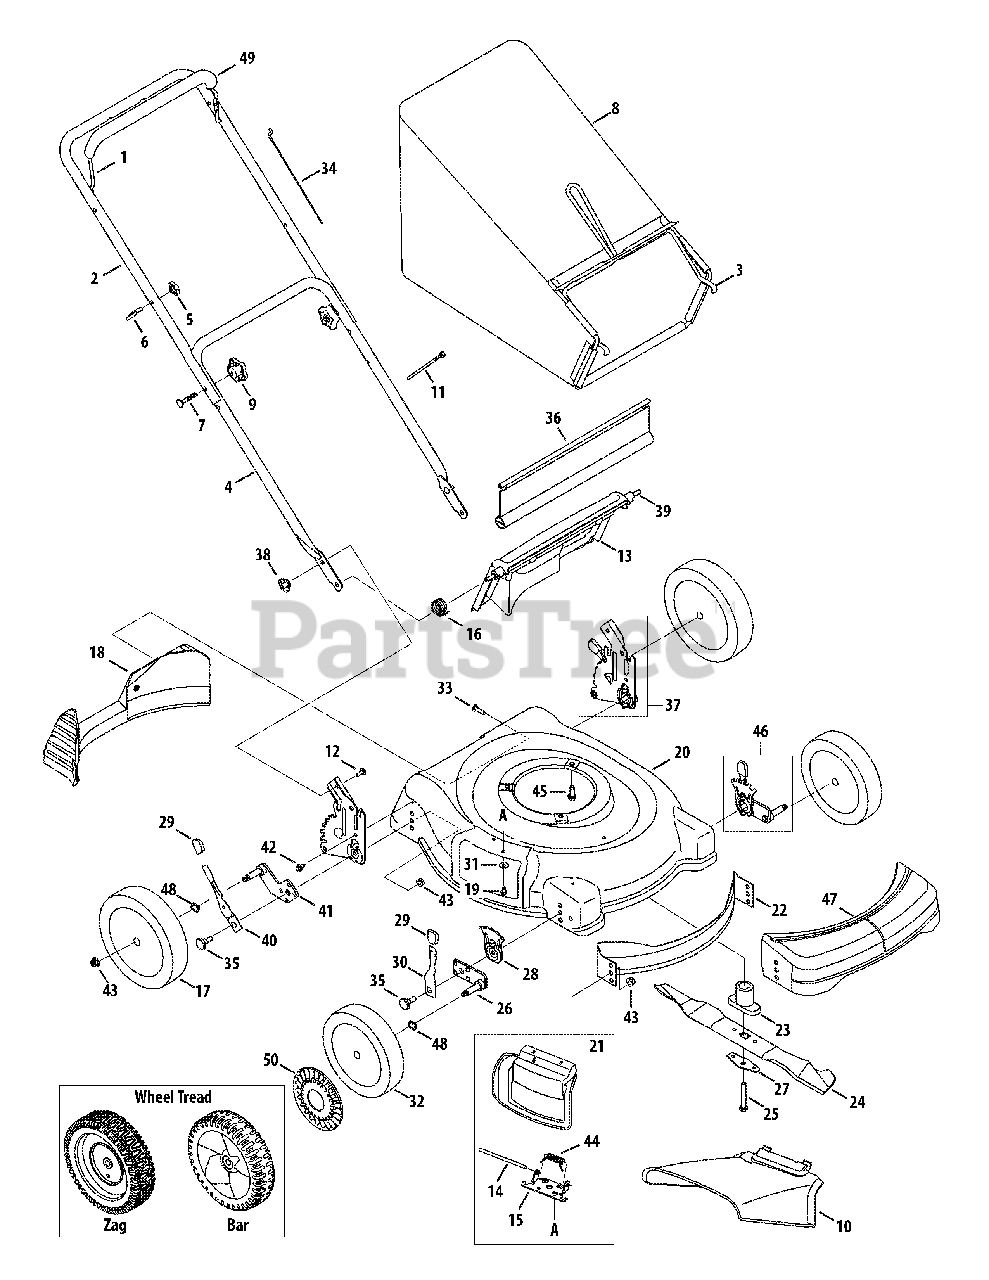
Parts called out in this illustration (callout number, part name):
1	Blade Control Handle
2	Upper Handle
3	Grass Catcher Frame
4	Lower Handle
5	Wing Nut
6	Rope Guide
7	Carriage Bolt ,5/16-18 x 2
8	Grass Bag - Gray
9	Hand Knob
10	Side Chute
11	Cable Tie
12	Carriage Bolt ,1/4-20
13	Rear Discharge Door
14	Hinge Pin
15	Deflector Chute Adaptor
16	Torsion Spring - RH
17	Rear Wheel, 8 x 2.125, Zag
18	Rear Baffle
19	Screw, 1/4-20 x .500
20	Deck - 21"
21	Hinged Mulch Plug Assembly
22	Front Baffle
23	Blade Adapter, #6 x 2.15
24	Mulching Blade
25	Hex Screw , 3/8-24 x 2.5
26	Pivot Arm Assy RH (8" wheel)
26	Pivot Arm Assy LH (8" wheel)
27	Blade Bell Support
28	Front Adjustment Plate
29	Adjustment Lever Knob
30	Spring Lever Assembly
31	Bell Washer
32	Front Wheel, 8 x 2.125, Zag
33	Screw, 1/4-15 x 1.000
34	Control Cable 40"
35	Shoulder Screw
36	Trailshield
37	Rear Handle Bracket Assy. - LH
37	Rear Handle Bracket Assy. - RH
38	Wing Nut, 1/4-20
39	Rear Door Pivot Rod
40	Spring Lever
41	Pivot Arm Assembly - RH
41	Pivot Arm Assembly - LH
42	AB Screw
43	Flange Lock Nut, 3/8-16
44	Torsion Spring
45	TT Sems Screw, 3/8-16 x 1.0
46	Height Adj. Assy. Front LH (8" wheel)
46	Height Adj. Assy. Front RH (8" wheel)
47	Front Cover
48	Wave Washer
49	Bail Cover - Gray
50	Hub Cap
